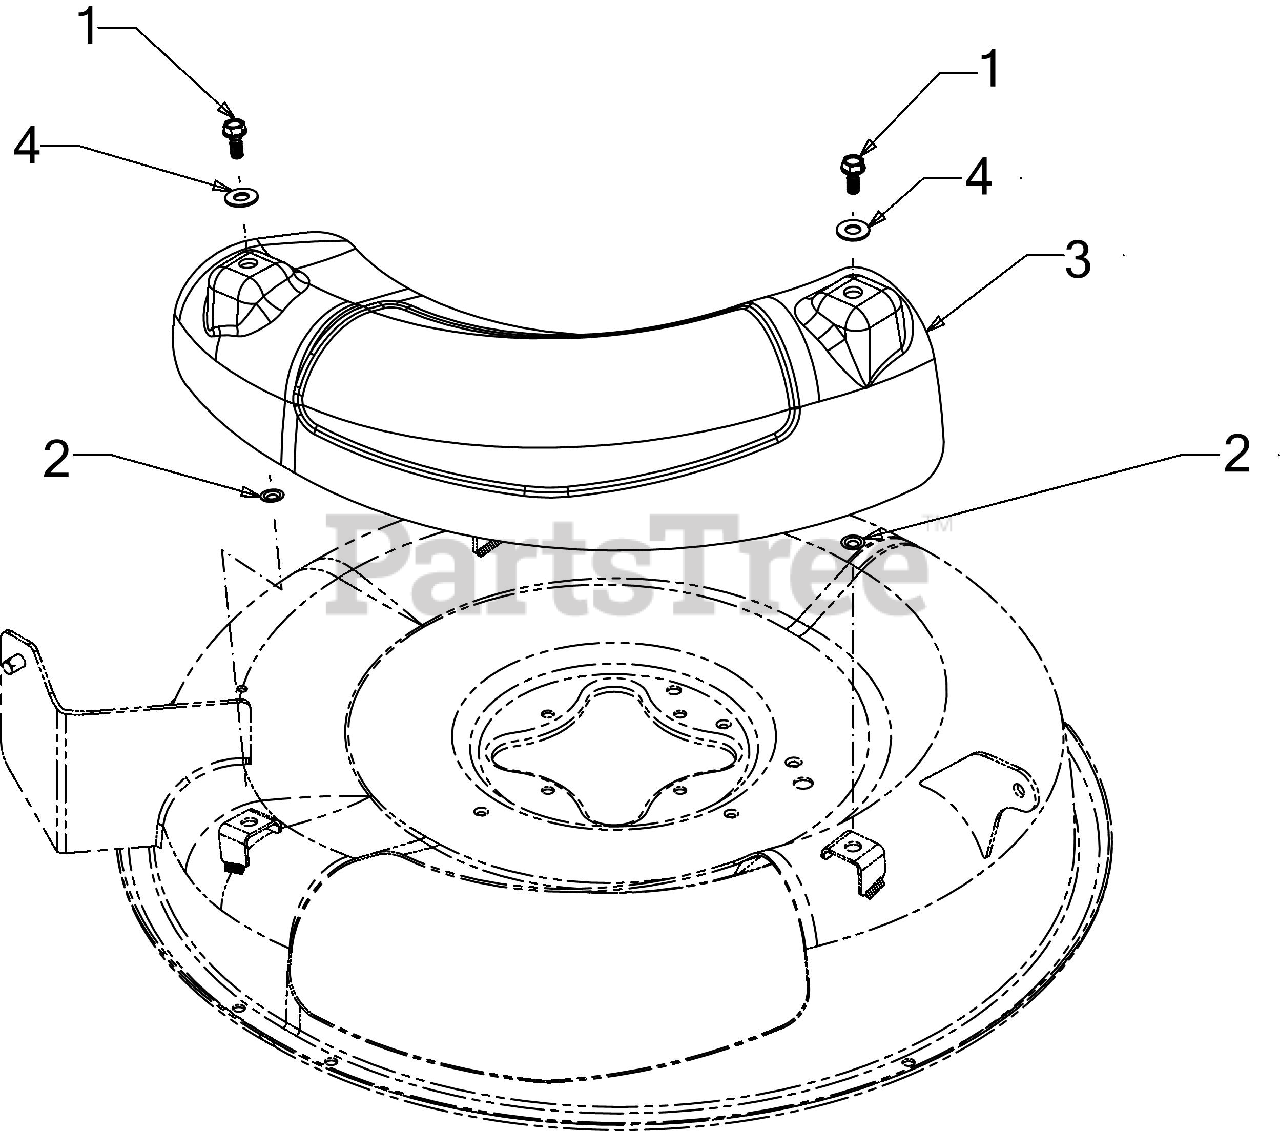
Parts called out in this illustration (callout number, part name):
1	HEX SCREW 5/16-18 x .750
2	PUSH NUT
3	MULCH PLUG
4	FLAT WASHER
